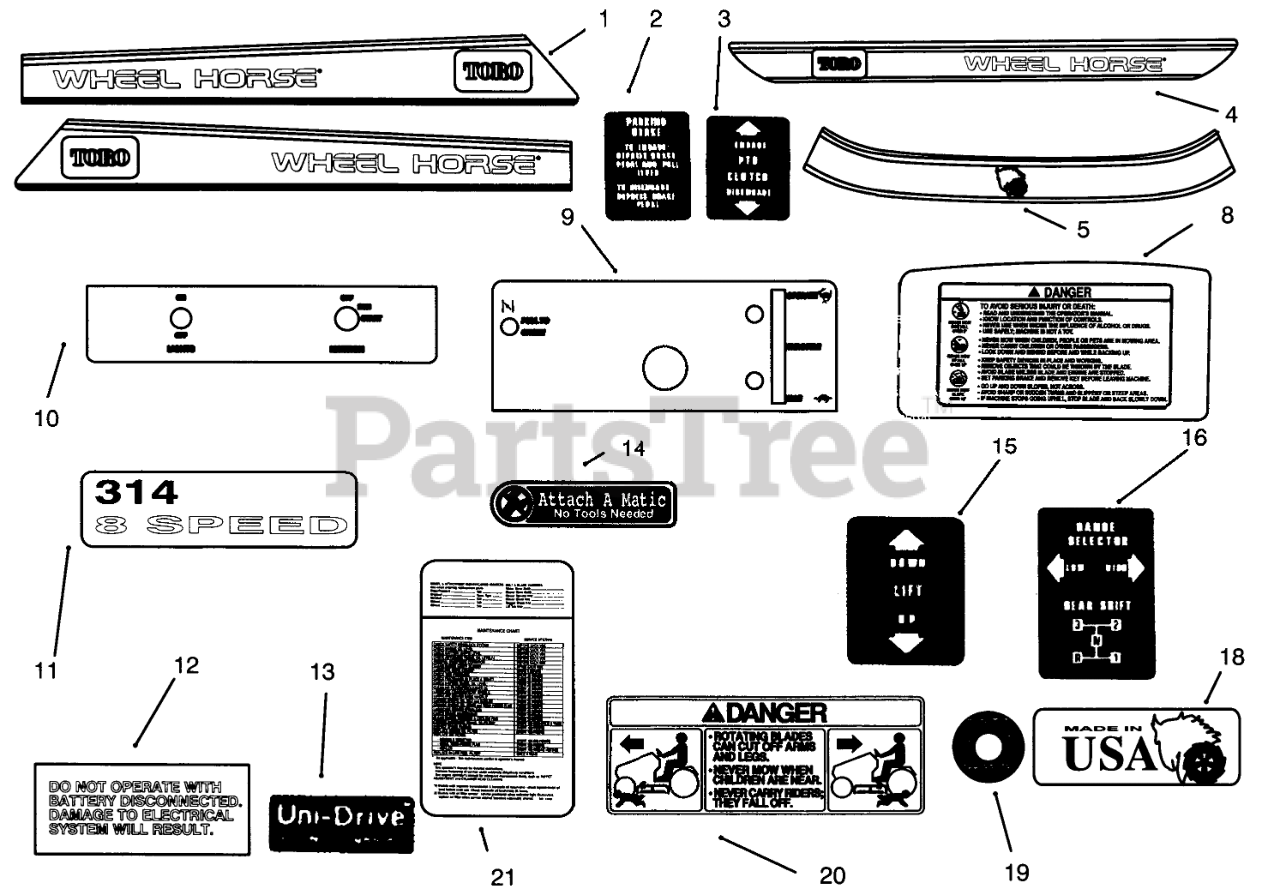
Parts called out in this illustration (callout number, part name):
1	DECAL - RH HOOD TOP
2	DECAL-PARKING, BRAKE
3	DECAL PTO CLUTCH
4	DECAL - REAR FENDER
5	DECAL-FRONT HOOD, TOP
8	DECAL - DANGER
9	DECAL-LOWER DASH
10	DECAL-BACK PLATE
11	DECAL - MODEL 314-8
12	DECAL ELECT SYSTEM
13	Decal-Unidrive
14	DECAL-ATTACH A-MATIC
15	DECAL-LIFT
16	DECAL-SHIFT PATTERN
18	DECAL - USA
19	Decal-Air Cleaner
20	DECAL-DANGER
21	Decal-Maintenance
